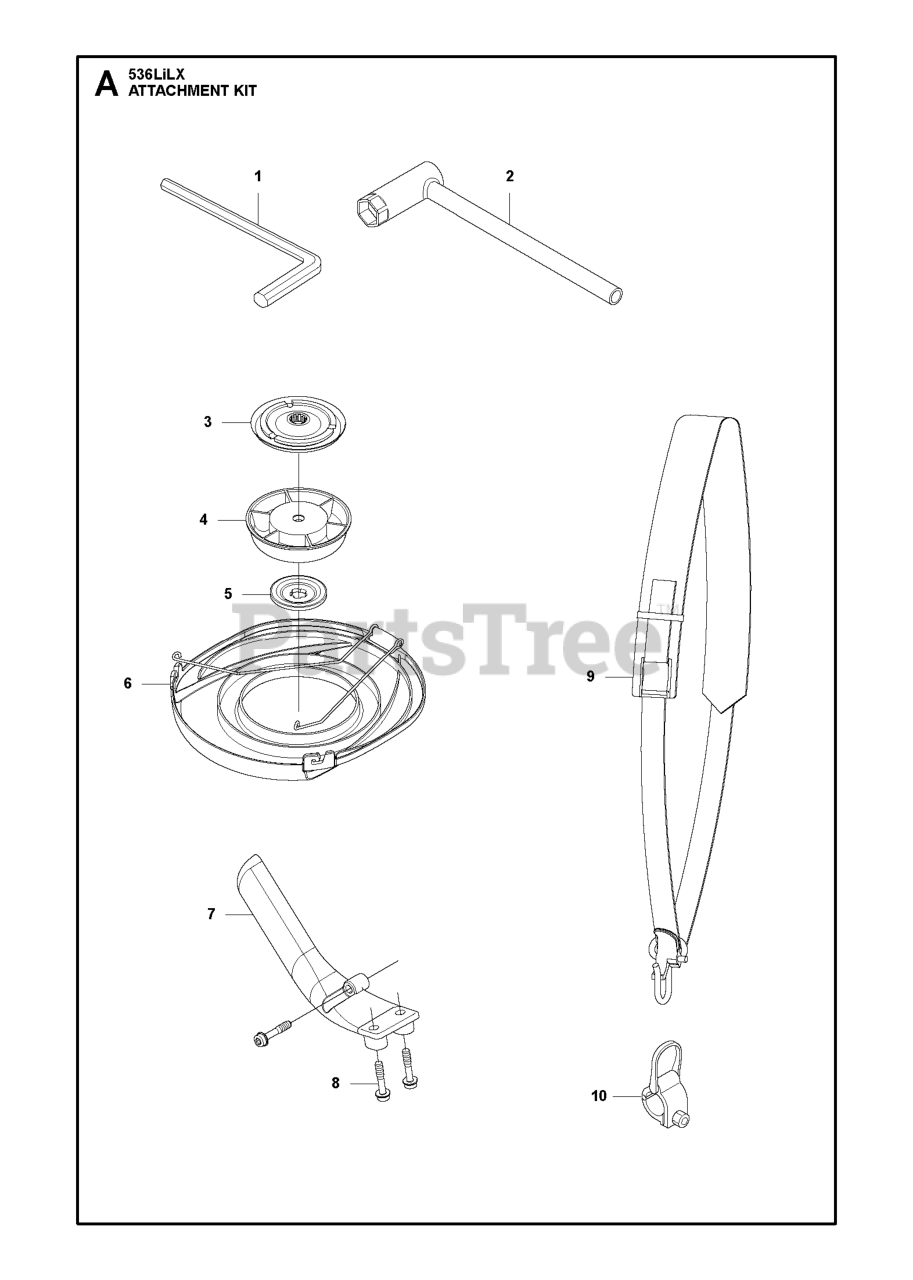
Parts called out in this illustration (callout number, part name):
2	COMBI WRENCH
3	DRIVER ASSY
4	SUPPORTING CUP
5	SUPPORT FLANGE
6	BLADE GUARD TRANSPORT
8	SCREW IHSCFTO
9	Harness-w/o warning
9	Harness - Diagonal with sign
10	HANGING BRACKET
